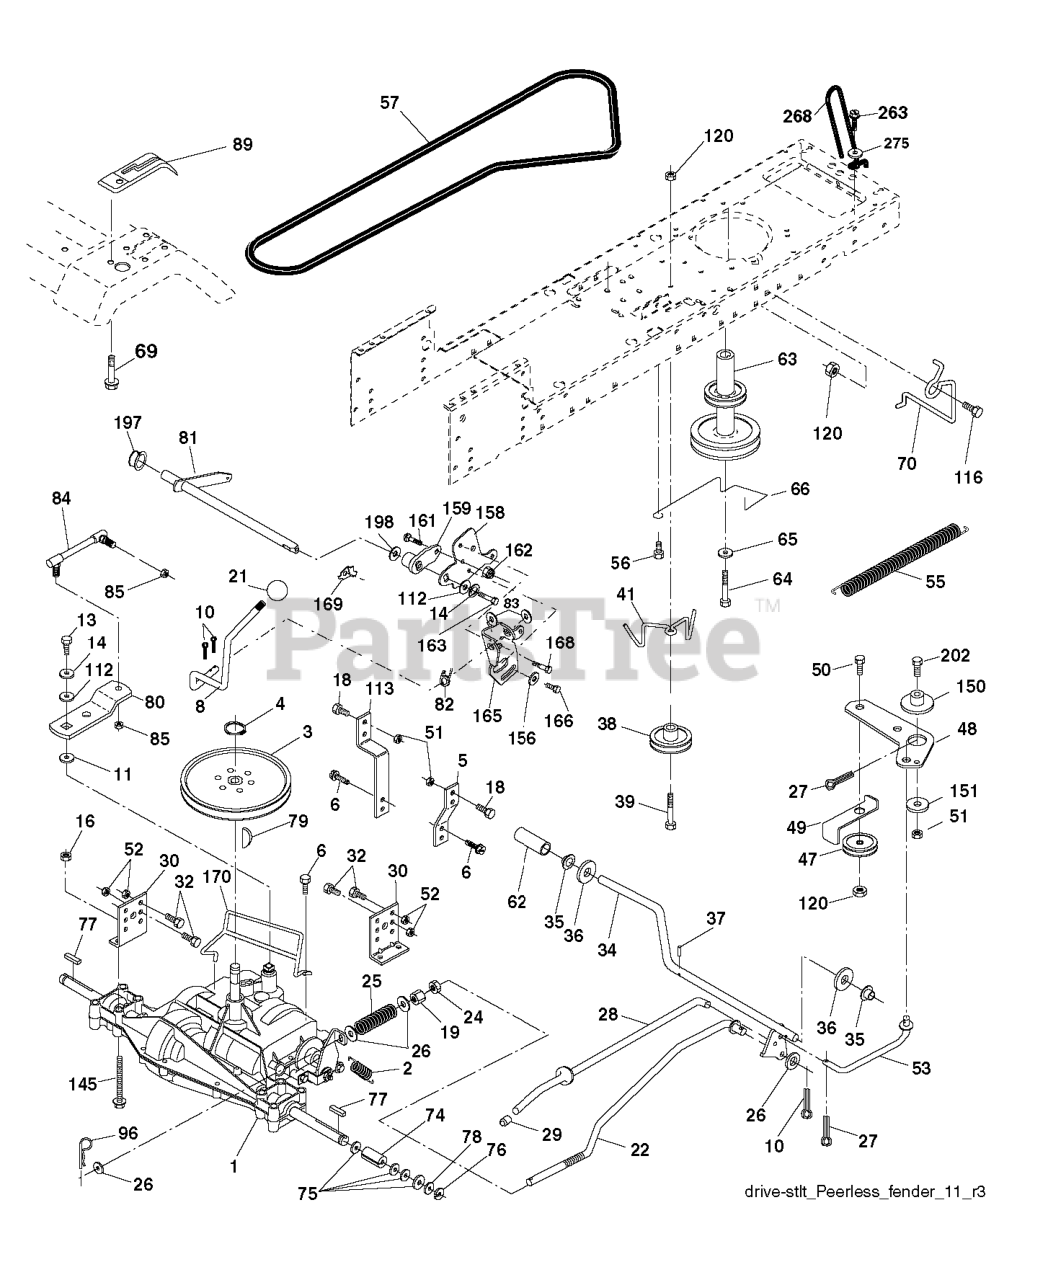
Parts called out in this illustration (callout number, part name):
2	SPRING,BRAKE RETURN
3	PULLEY TRANS
4	RETAINING RING LT
5	STRAP TORQUE
6	SCREW 5/16"
8	ROD SHIFT FENDER ADJUST LT
10	PIN COTTER
11	WASH-SHFT PLT LT
13	BOLT 1/4-28X3/4
14	LOCKWASHER
16	NUT.71038.31-18.HEX.NYLOCK
19	NUT
21	KNOB T (1/2-HOLE)
24	NUT
25	SPRING ROD LT
26	WASHER
27	COTTER PIN
28	ROD, PARKING BRAKE
29	PLUNGER CAP
30	BRKT, MOUNT TRNSAXLE
32	BOLT
34	SHAFT, FOOT PEDAL
35	BEARING.NYLON
37	DRIVE PIN
38	PULLEY IDLER COMPOSITE
41	KEEPER, BELT IDLER
47	IDLER PULLEY
48	BELLCRANK, CLUTCH
49	RETAIN BELT
50	BOLT.3/8-16X1.50
52	LOCKNUT
53	LINK.CLUTCH.7.66.2005
55	SPRING, RETURN LT
56	SCREW.3/8-16
57	BELT, V GROUND DRIVE 95 25
62	PEDAL COVER T
63	ENGINE PULLEY
64	BOLT HEX 7/16-20X4-1/4"
65	LOCKWASHER
66	KEEPER BELT ENGINE
69	SCREW.HI-LO.CONSOLE
70	KEEPER BELT ENG
74	SPACER AXLE
77	SQUARE KEY
79	KEY STD (1373) DANA
81	SHAFT ASM CROSS TAPERED
82	SHIFT SPRING
83	WASHER
84	LINK.TRNSAXLE
85	NUT LOCK CENTER 1/4 -28 FNTHD
89	CONSOLE SHIFT STLT
96	RETAINER M
113	STRAP TORQUE LH LT
116	BOLT D
120	NUT LOCK FLG 3/8-16 UNC
150	SPACER, RETAINER
151	WASHER 12/32X2X10GA
156	WASHER.SRRTD.5/16
158	BRACKET.SHIFT.MOUNT
159	RB HUB.SHIFT
161	BOLT
162	NUT.CROWNLOCK.1/4
165	BRACKET.PIVOT.LEVER
166	CAPSCREW.HXHD.FLG.5/16-18X.625
168	BOLT.SHOULDER.5/16-18X
169	PLATE.FASTENING.CROSS.SHAFT
170	KEEPER BELT T/A
197	NYLINER SNAP 5/8" ID
198	WASHER.NYL.7/8IDX.105"HYD CR
263	SCREW, 3/8-16X3/4
268	GUARD MUFFLER
275	WASHER
